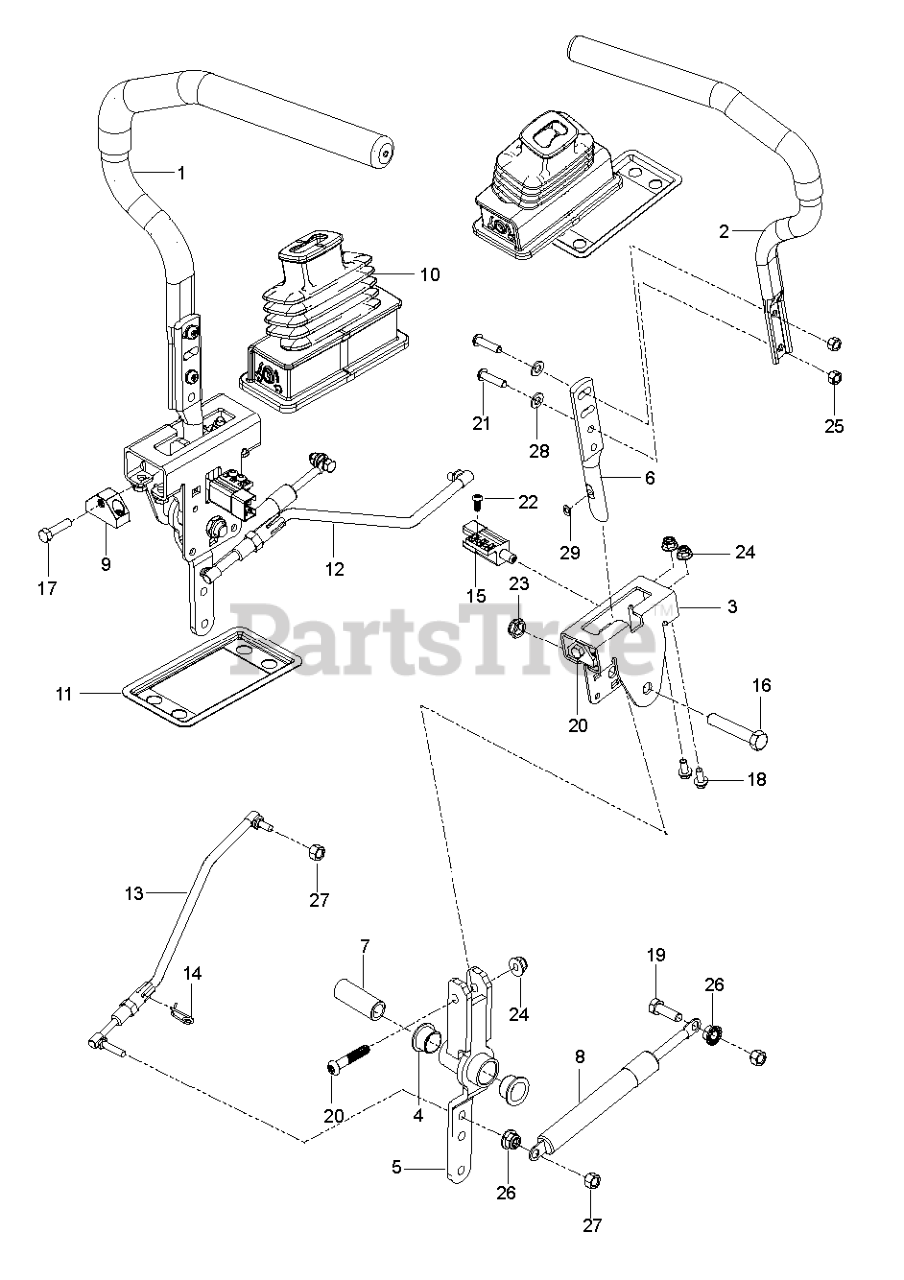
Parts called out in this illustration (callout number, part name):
1	TUBE.LEVER.CNTL.ASM.ZTR.RT.SVC
2	TUBE.LEVER.CNTL.ASM.ZTR.LT.SVC
3	BRACKET.CONTROLS.ZTR.X431
4	BEARING, FLANGE
5	LEVER CONTROL PIVOT
6	CONTROL.LEVER.HANDLE
7	SPACER.PIVOT.CONTROL
9	BLOCK TRACKING CONTROL ZTR
10	BOOT.STEERING.LEVER
11	CONTROL.BOOT.FLANGE.X431
12	ROD.ASM.RH.ADJUSTABLE
13	ROD.ASM.LH.ADJUSTABLE
14	RETAINER.CLIP.SPRING.S
15	SWITCH.INTLK.RZ.RFRSH.BUTTON
16	HCS 1/2-13 X 2-3/4 GD 5 ZD
17	SCREW.SHAKEPROOF.1.25.BLACK
18	HHFS 5/16-18 X 3/4
19	HCS 5/16C X 1
20	SCREW.CAP.SOCKET.6PT.5/16-18
21	BUTTONHEAD.5/16-18X1.125.BLACK
22	SCREW.BUTTONHD.10-24X1/2.(2 2)
23	NUT 1/2-13 HEX JM NYL
24	5/16-18 NYLOC FLANGE NUT
25	NYLOCK.NUT.5/16-18 BLACK
26	NUT 5/16C WHIZ
27	NUT.71038.31-18.HEX.NYLOCK
28	WASHER
29	WASHER.11/32ID.11/16OD.116THIC
